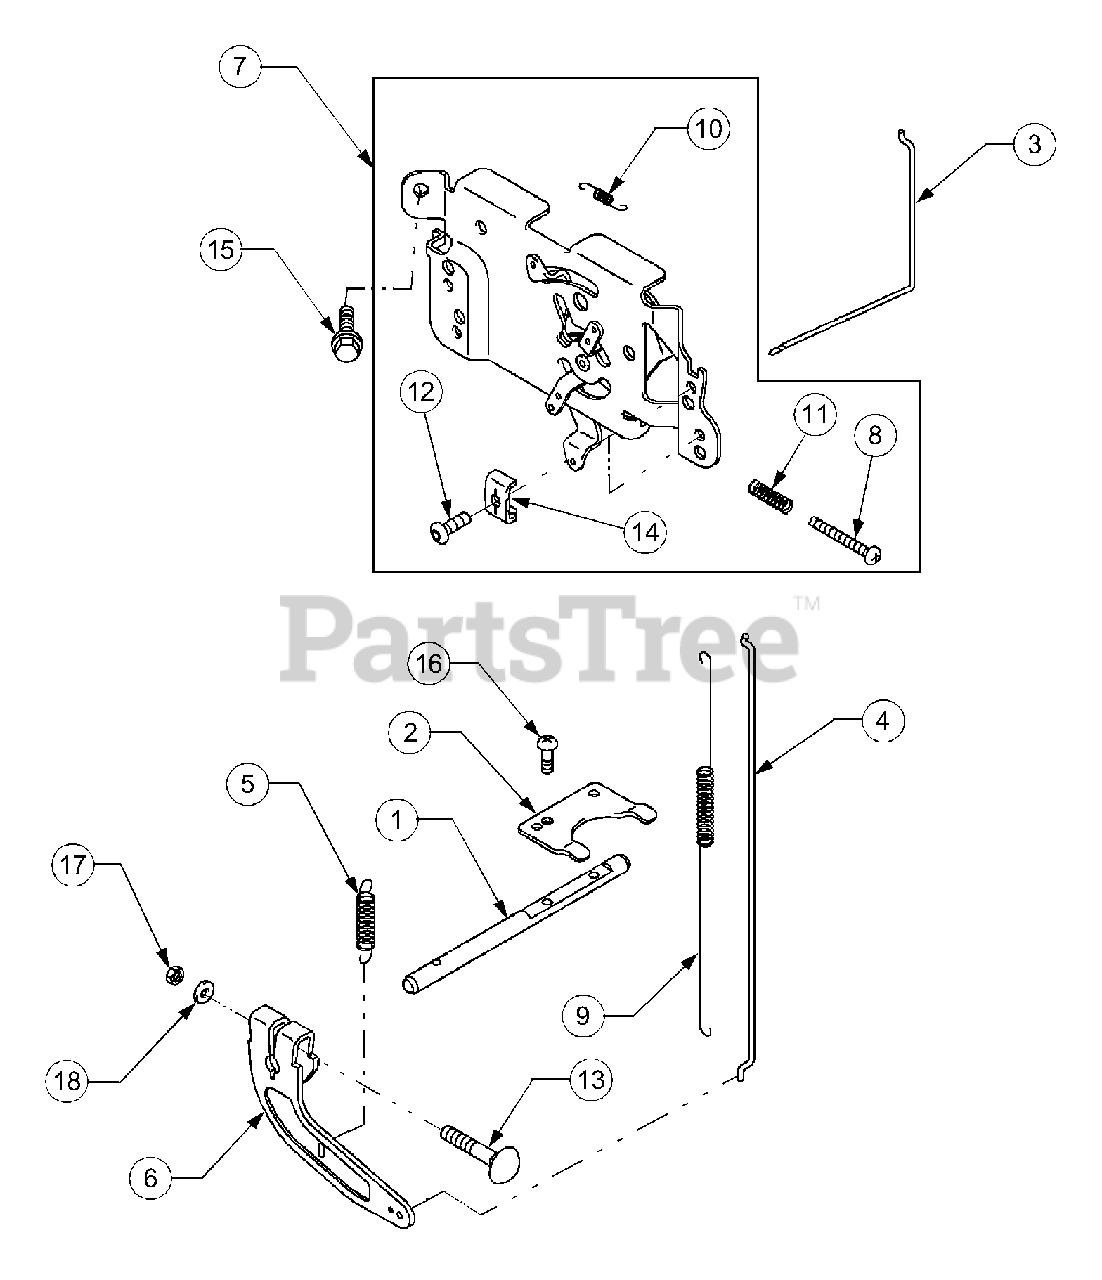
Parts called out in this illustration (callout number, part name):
2	Plate
3	Link, Choke
5	Spring, Governor
6	Arm, Governor
7	Panel, Control Comp
10	Spring
12	Screw, Hx, 5x16
13	Bolt, 6x35
15	Bolt, Flanged
16	Screw, Pan
17	Nut, Hex
18	Washer, Plain
